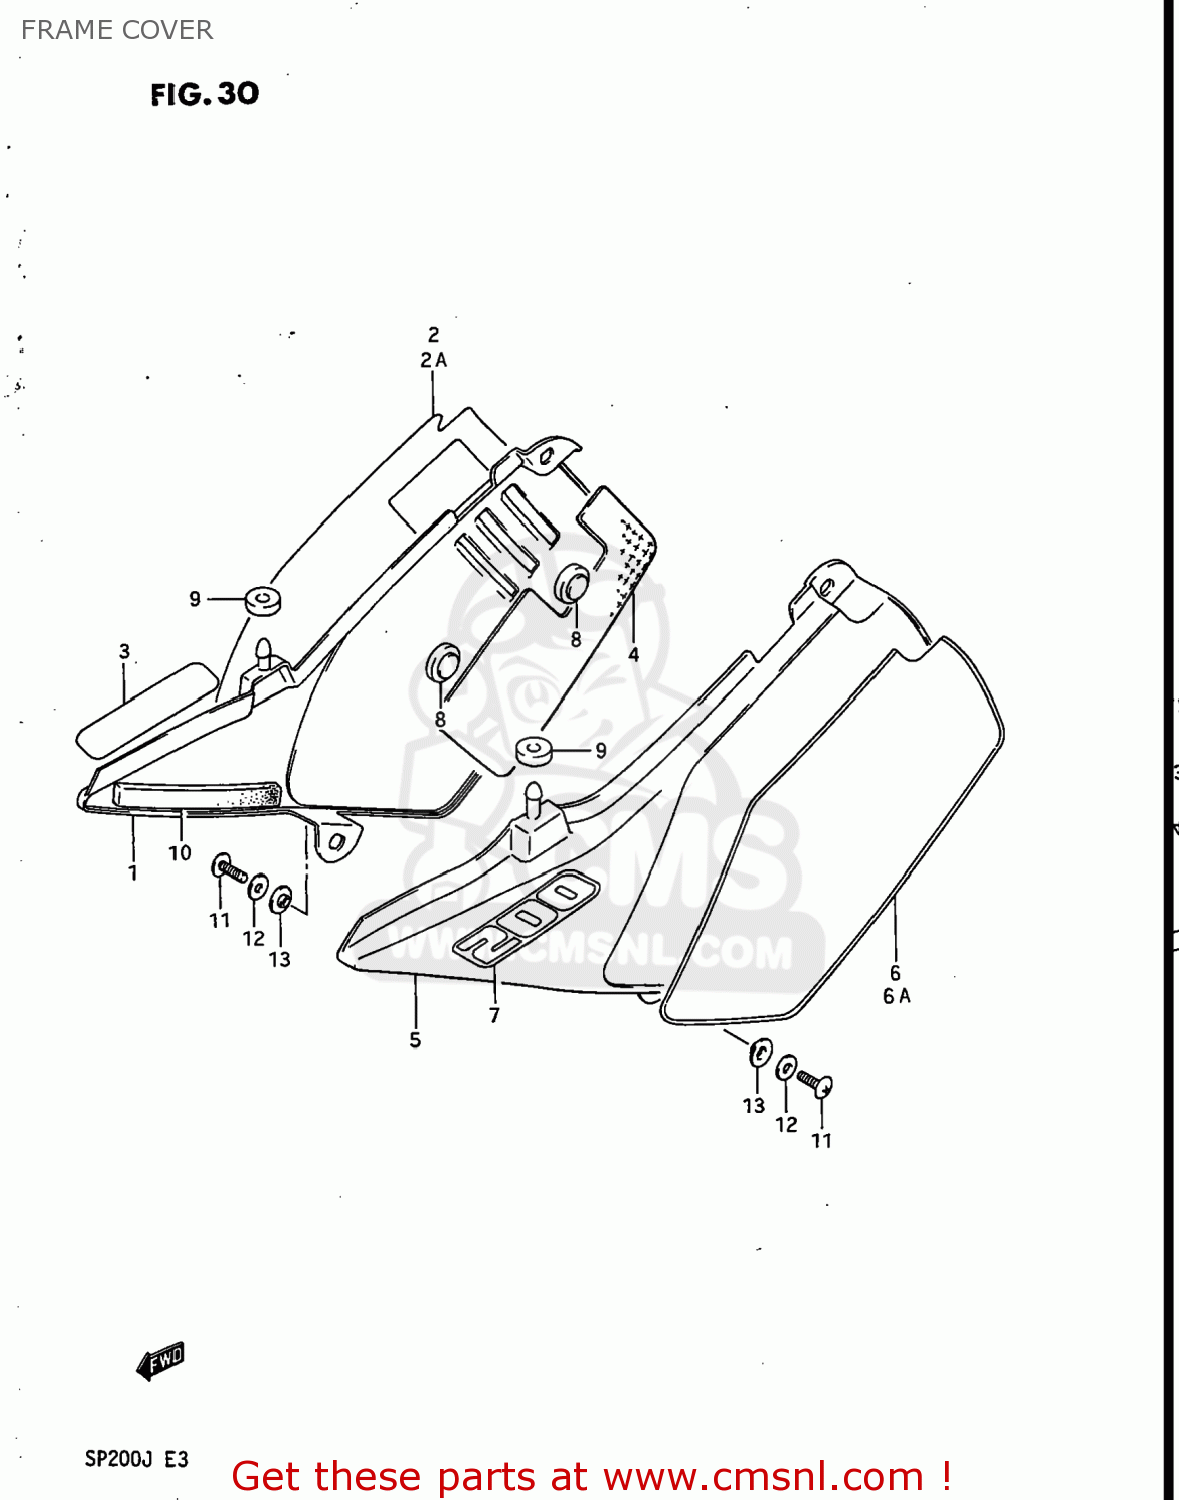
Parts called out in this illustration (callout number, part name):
1	COVER,FRAME,RIGHT
2	TAPE SET,FRAME COVER
2A	TAPE,FRAME COVER,RIGHT (WHITE)
3	EMBLEM
4	SHIELD,FRAME COVER,RIGHT
5	COVER,FRAME,LEFT
6	TAPE SET,FRAME COVER
6A	TAPE,FRAME COVER,LEFT (WHITE)
7	EMBLEM
8	CUSHION
9	CUSHION,SIDE COVER BOSS
10	CUSHION,FRAME COVER
11	SCREW
12	WASHER (6.5X18X1.6)
13	WASHER
